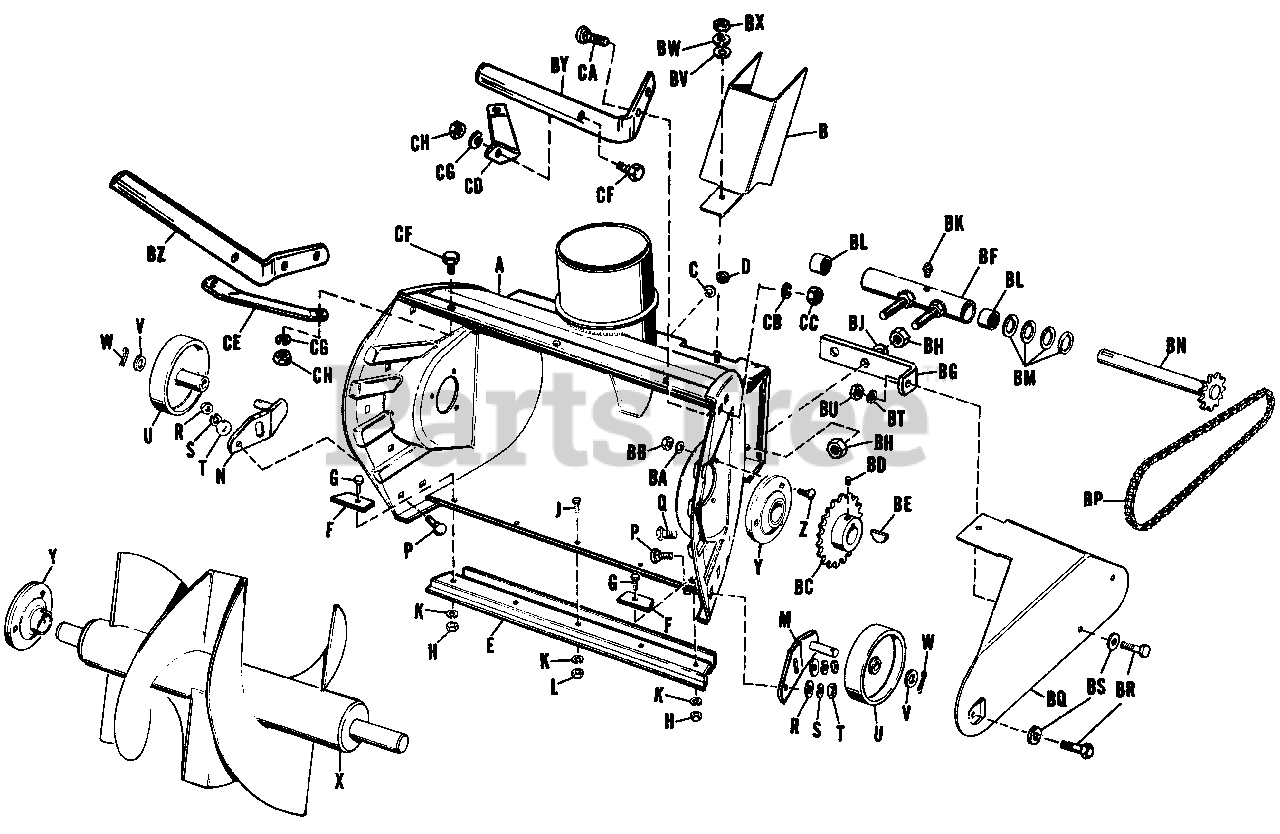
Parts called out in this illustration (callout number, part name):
A	Body Assembly
B	Belt Cover
C	Lock Washer, 3/8"
D	Hex Nut, Full, 3/8"-16
E	Scraper Body
F	Clamp, Scraper
G	Hex. Capscrew, 5/16"-18 x 7/8" lg.
H	Hex Nut, Full, Lock, 5/16"-18
J	Hex Capscrew, 1/4"-20 x 5/8" lg.
K	Lock Washer, 1/4"
L	Hex Nut, Full, 1/4"-20
M	Roller Bracket Assembly, LH
N	Roller Bracket Assembly, RH
P	Carriage Bolt
Q	Hex Capscrew, 3/8"-16 x 7/8" lg.
R	Plain Washer, 3/8"
S	Lock Washer, 3/8"
T	Hex Nut, Pull, 3/8"-16
U	Roller Assembly
W	Cotter Pin, 1/8" x 1-1/4" long
X	Rotor Assembly
Y	Ball Bearing
Z	Hex Capscrew, 5/16"-18 x 3/4" lg.
BA	Lock Washer, 5/16"
BB	Hex Nut, Full, 5/16"-18
BC	Rotor Sprocket
BD	Set Screw, Cup Pt., 5/16"-18 x 5/16"
BF	Housing Assembly, Bearing
BG	Chain Guard Bracket
BH	Hex Nut, Full, 1/2"-13
BJ	Washer, Plain, 1/2"
BK	Fitting, Grease
BL	Needle Bearing
BN	Shaft Assembly
BP	Rotor Chain
BQ	Chain Guard
BR	Hex Capscrew, 5/16"-18 x 5/8" lg.
BS	Plain Washer, 5/16"
BT	Lock Washer, 5/16"
BU	Hex Nut, Full, 5/16"-18
BV	Plain Washer, 3/8"
BW	Lock Washer, 3/8"
BX	Hex Nut, Full, 3/8"-16
